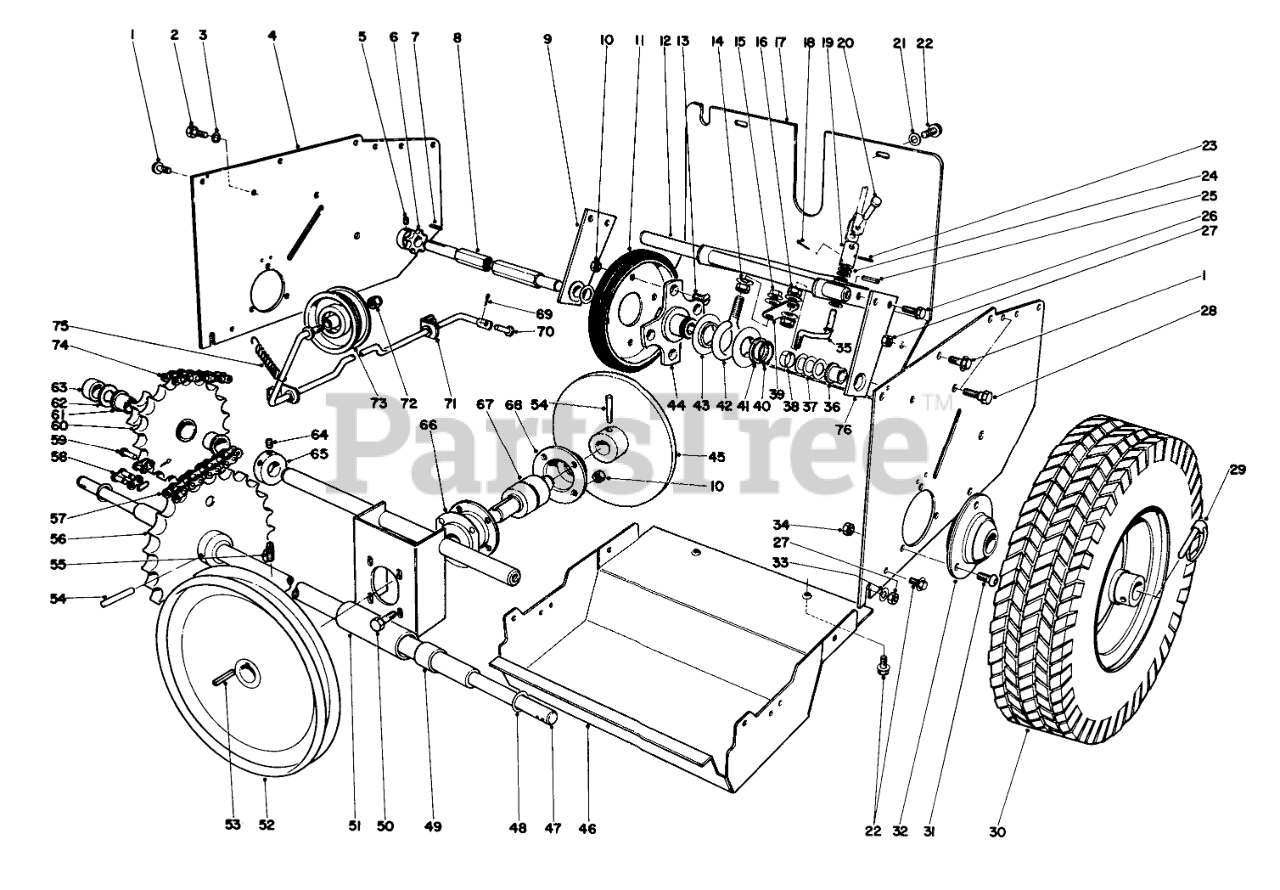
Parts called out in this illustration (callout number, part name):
1	SCREW-HHF
2	SCREW-HH
3	WASHER-LOCK
4	Side Plate
5	Set Screw
6	SPROCKET
8	FRICTION WHEEL SHAFT
9	Hex Shaft Mount (Incl. Ref. 36)
10	Nut
11	Disc
12	Bracket Dead Shaft
13	5/16-18X5/8 FLT HD MS
14	WASHER-SPRING
15	NUT-LOCK, FLANGE
16	Nut
17	REAR COVER R
18	PIN-COTTER
19	U JOINT TUBE
20	CLEVIS PIN
21	WASHER-FLAT
22	Screw, Self-tapping
23	PIN-SPRING
24	Spacer
25	PIN-ROLL
26	Hex Hd. Screw
27	NUT-HEX
28	SHOULDER SCREW
29	PIN-LYNCH
30	Wheel
31	SCREW-HSBH
32	Bearing Flange
33	WASHER-FLAT
34	NUT-LOCK
35	CONNECTION ROD
36	BUSHING
37	WASHER-FLAT
38	SPLIT SPACER
39	SHIFT ROD PIVOT
40	RING-RETAINING
41	WASHER-THRUST
42	SLIDER RING COLLAR
43	SLIDER RING
44	Hub Traction Disc
45	FRICTION PLT WA
46	LOWER SHIELD R
47	Axle Shaft
48	WASHER
49	Bushing
50	SCREW-HH
51	Bulkhead (Incl. Ref. 49)
52	Pulley
53	KEY-SQUARE
54	Groove Pin
55	SCREW-SET, SQH
56	Sprocket
57	Chain Lower
58	LINK-CONNECTING
59	1/4 OFFSET LINK
60	Sprocket (Incl. Ref. 61)
61	3/4ID X 3/4LG BSHG
62	WASHER-THRUST
63	Spacer Idler
64	SCREW-HSH
65	Collar
67	Friction Plate Shaft
68	HOUSING BEARING
69	PIN-COTTER
70	PIN-CLEVIS
71	Clutch Rod
73	PULLEY-IDLER
74	1/4 X 42 CHAIN W/LINK
75	EXTENSION SPRING
76	Hex Shaft Mount (Incl. Ref. 36)
